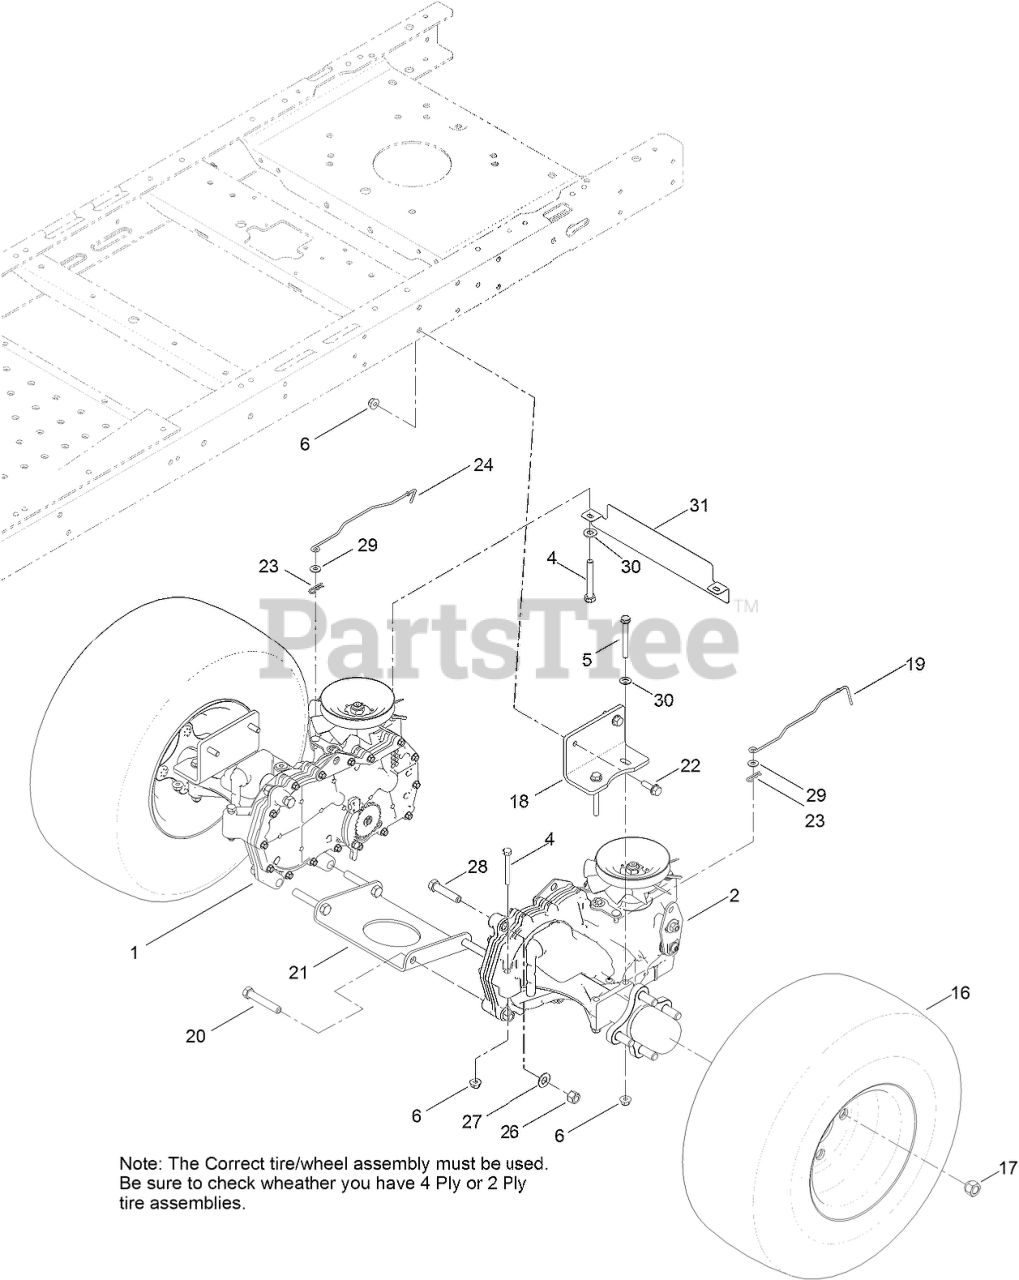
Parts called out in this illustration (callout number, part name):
1	RH HYDRO TRANSAXLE ASM
2	LH HYDRO TRANSAXLE ASM
4	SCREW-HH
5	SCREW-HH
6	NUT-HF, NI
16	4 PLY WHEEL AND TIRE ASM
16	2 PLY TIRE AND WHEEL ASM
17	NUT-LUG
18	MOUNT-HYDRO
19	ROD-BYPASS, LH
20	SCREW-HH
21	PLATE-CROSS, HYDRO
22	SCREW-HHF
23	PIN-COTTER
24	ROD-BYPASS, RH
26	NUT-LOCK, NI
27	WASHER-FLAT
28	SCREW-HH
29	WASHER
30	WASHER-PLAIN
31	GUARD REAR, WIDE
